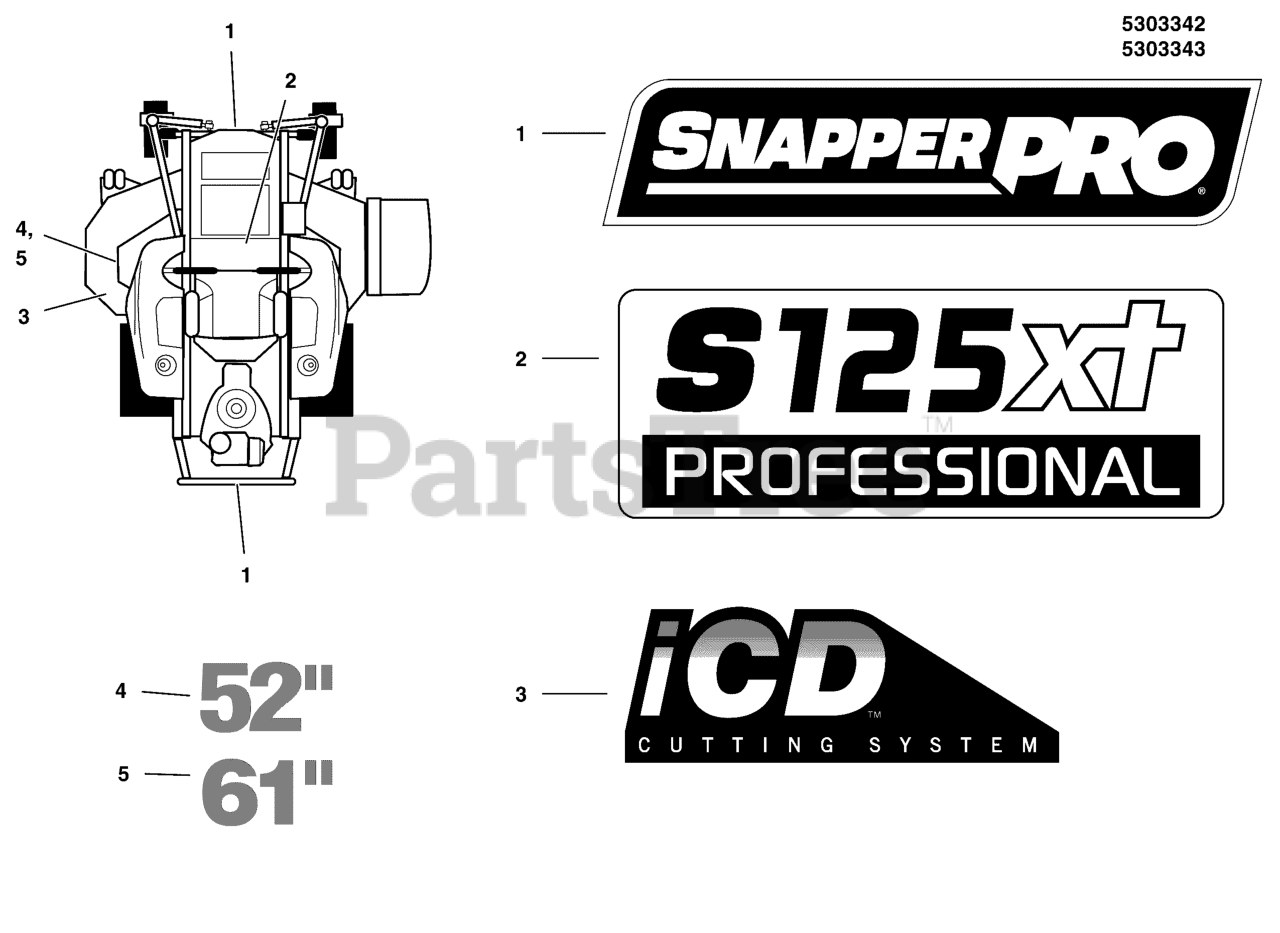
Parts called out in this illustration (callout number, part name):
1	DECAL, SNAPPER PRO LOGO, SMALL
2	DECAL, SNAPPER PRO, S125XT
3	DECAL, iCD CUTTING SYSTEM
4	DECAL, 52
5	DECAL, 61
